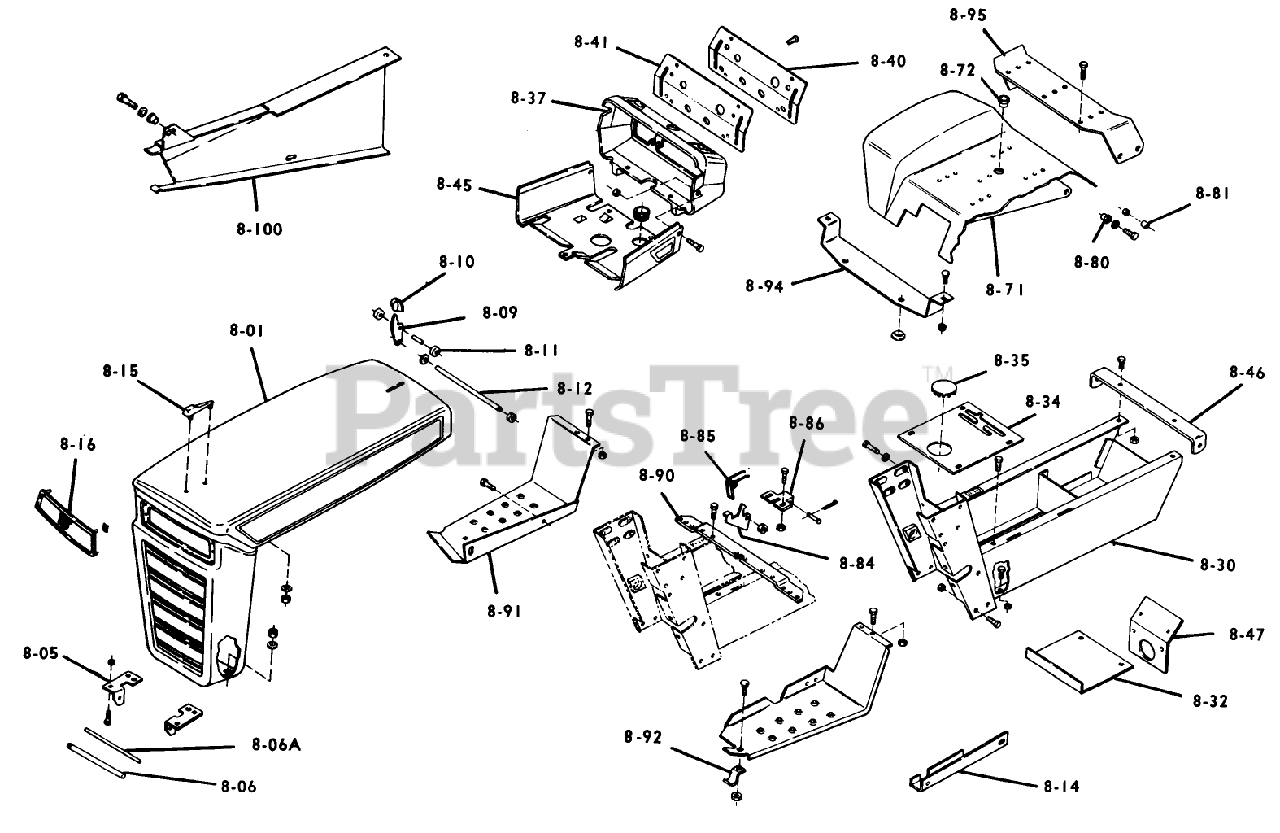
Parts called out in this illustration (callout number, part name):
8-06	GRILL PIVOT ROD
8-06A	ROD-HOOD STOP
8-09	LEVER HOOD LATCH
8-10	KNOB
8-15	Hood Ornament
8-16	ESCUTCHEON PLATE
8-32	Cover-Dust
8-80	BUSHING-FLANGED
8-85	Spring
8-92	BRACKET
